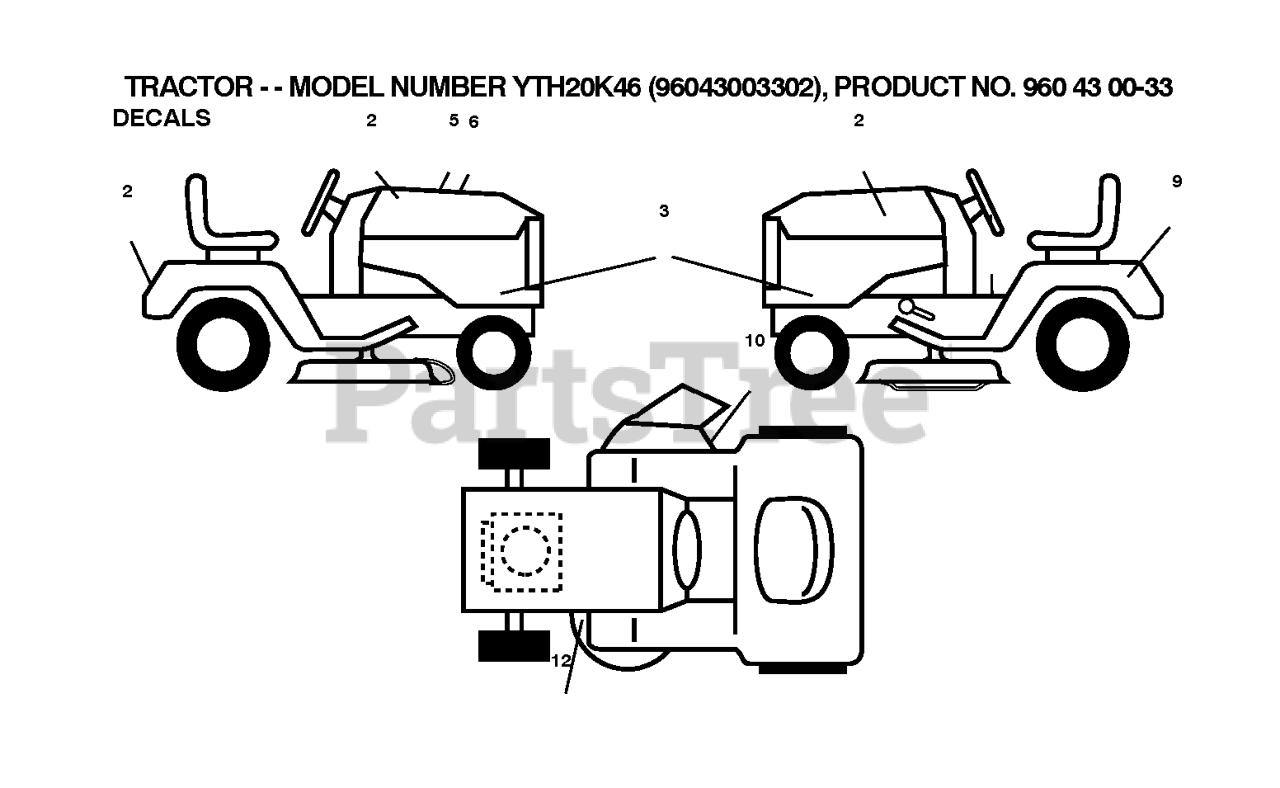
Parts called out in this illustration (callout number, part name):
1	DECAL.FENDER.WARNING.ENG
2	DECAL.HOOD.LOGO.ORANGE.HUSQVAR
3	DECAL, HOOD PANEL SD
5	DECAL HOOD CUST. RESP.
9	DECAL BTRY SYMBOLS
10	DECAL.WARN.KEEP.HAND.AWAY
12	DECAL V BELT SCHEMATIC
